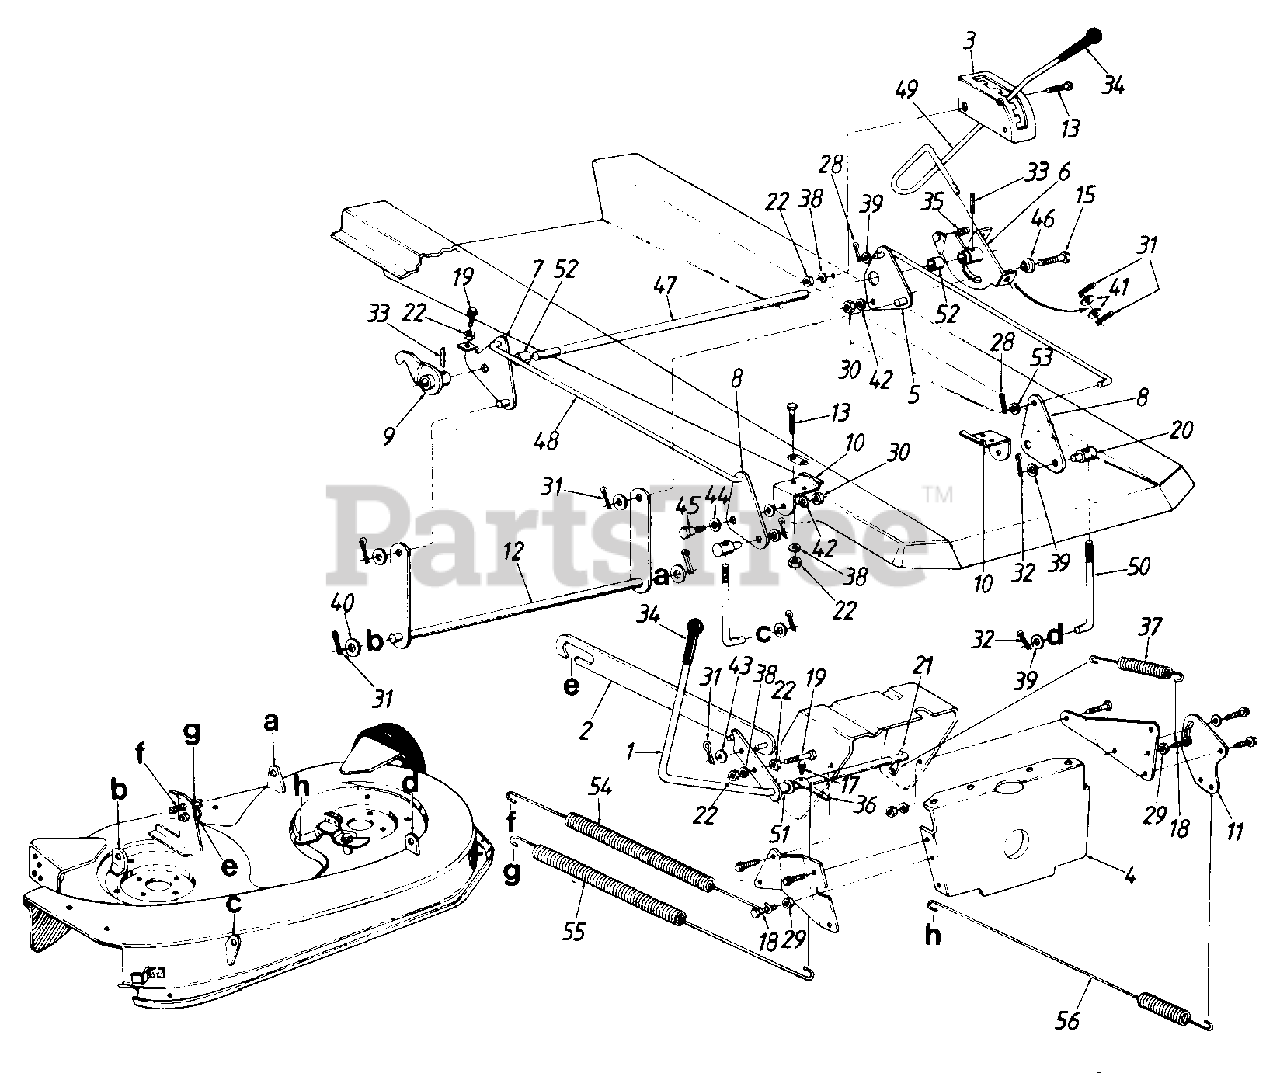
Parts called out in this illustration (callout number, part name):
1	Blade Engagement Lever Ass'y.
2	Deck Drive Control Brkt. A ss'y.
5	Deck Lift Brkt. Ass'y.
6	Deck Lift Handle Retainer Ass'y.
7	Deck Lift Brkt. Ass'y.
8	Deck Lift Bracket
9	Deck Lift Float Brkt Ass'y.
10	Deck Lift Pivot Brkt.
11	Blade Brake Spring Brkt.
12	Stabilizer Shaft Ass'y.
13	Hex Bolt 5/16-18 x .75" Lg.
15	Hex Bolt 3/8-16 x 1" Lg.
17	Hex Wash. Hd. Scr. 1/4-20 x 1.5" Lg.
18	Hex Bolt 5/16-18 x 1-l/2" (Gr. 5)
19	Hex Wash.-Tap Scr. 5/16-18 x 1.25" Lg.
20	Ferrule
21	Clevis Pin (Special)
22	Hex Nut 5/16-18 Thd.*
28	Cotter Pin 3/32" Dia.
29	Hex Nut 1/4-20 Thd.
30	Hex Nut 3/8-16 Thd.
31	Cot-Pin 1/8" Dia. x 1" Lg.
32	Int. Cot. Pins 3/8" Dia.
33	Spring Pin Spir. 1/4" Dia.
35	Compression Spring 1.04" Lg.
36	Switch Actuator
37	Ext. Spring 5.86" Lg.
38	L-Wash 5/16" I.D.
39	Fl-Wash. .385 I.D. x .62
40	Fl-Wash. .635 I.D. x 1.12
41	Fl-Wash. .531 I.D. x .930
42	L-Wash. 3/8" I.D.*
43	Fl-Wash. .385 I.D. x .87 O.D.
44	Spring Washer .530 I.D.
45	Shld Bolt .500" Dia. x .215" Lg.
46	Shld. Spacer .625" I.D.
47	Rear Hot Adj. Shaft
50	J-Bolt 5.4" Lg.
51	Spacer.511 I.D.
52	Spacer .885 I.D.
53	Fl-Wash. 5/16" I.D.*
54	Ext. Spring 22.05" Lg.
55	Ext. Spring 13.84" Lg.
56	Ext. Spring 15.38" Lg.
